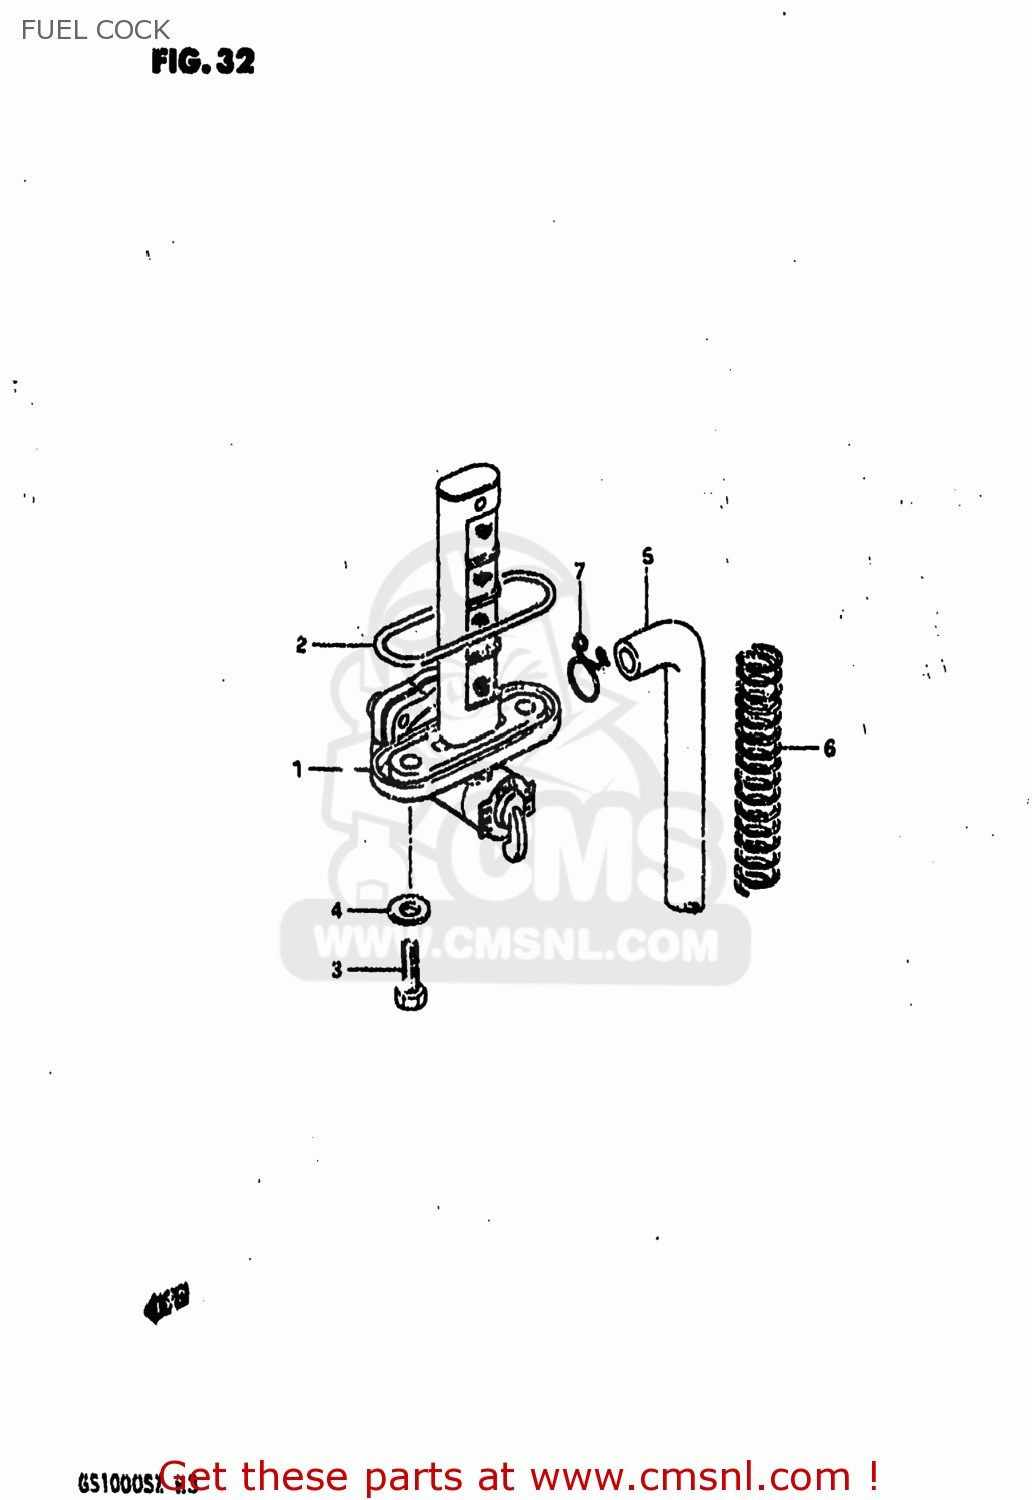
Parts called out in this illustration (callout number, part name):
1	COCK ASSEMBLY,FUEL
2	O RING
3	BOLT(6X20)
4	GASKET
5	HOSE
6	SPRING
7	CLIP
